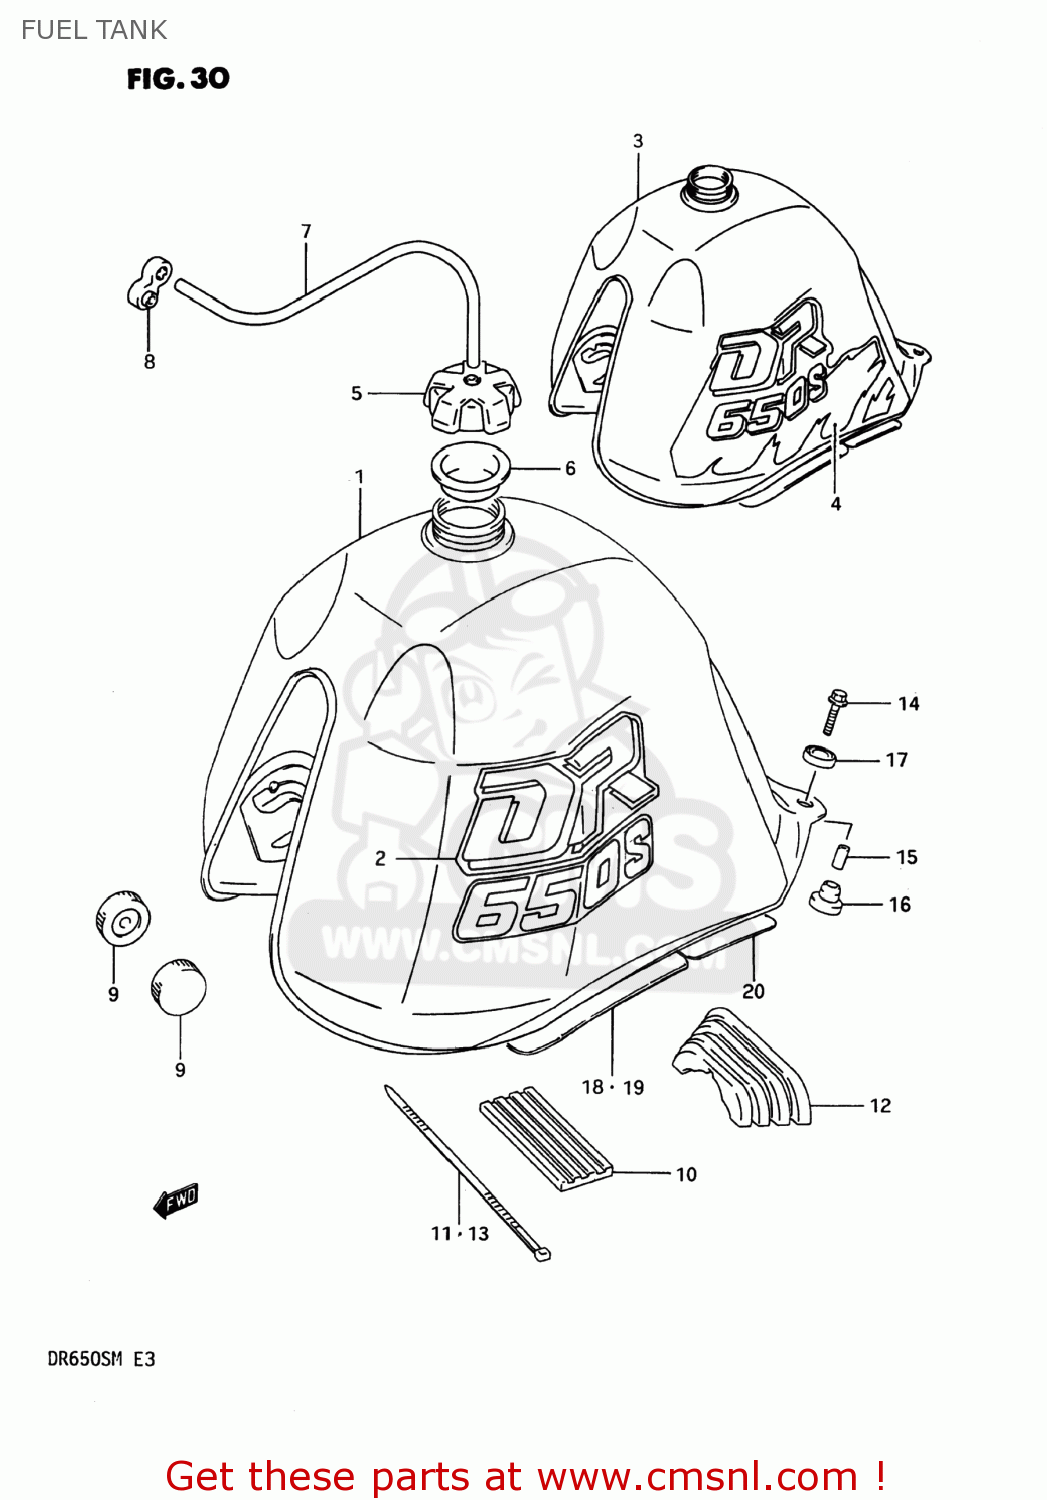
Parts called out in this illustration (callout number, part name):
1	TANK ASSEMBLY,FUEL
2	EMBLEM,FUEL TANK
3	TANK ASSEMBLY,FUEL
4	TAPE SET,FUEL TANK STRIPE
5	CAP SET,FUEL TANK
6	GASKET,FUEL TANK CAP (NAS)
7	HOSE
8	CLAMP,FUEL TANK BREATHER HOSE
9	CUSHION
10	CUSHION,FUEL TANK UPR FR
11	CLAMP
12	CUSHION,FUEL TANK RR
13	CLAMP(L:300)
14	BOLT
15	SPACER
16	CUSHION
17	CUSHION
18	SHIELD,FUEL TANK,RIGHT
19	SHIELD,FUEL TANK,LEFT,FRONT
20	SHIELD,FUEL TANK,LEFT,REAR
